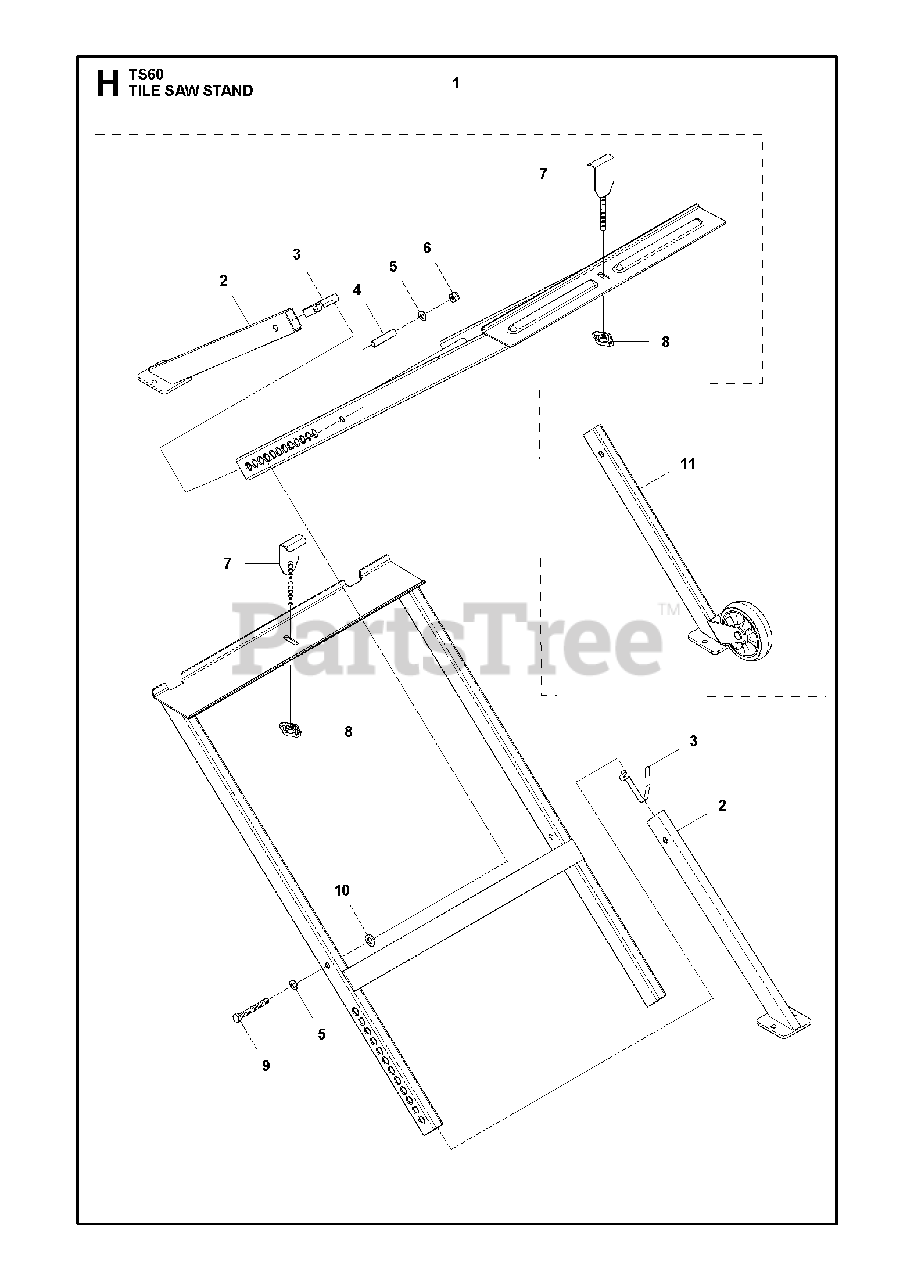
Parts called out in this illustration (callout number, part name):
5	WASHER
6	HEXAGON LOCKING NUT
10	WASHER
11	WHEEL KITNOT STANDARD
